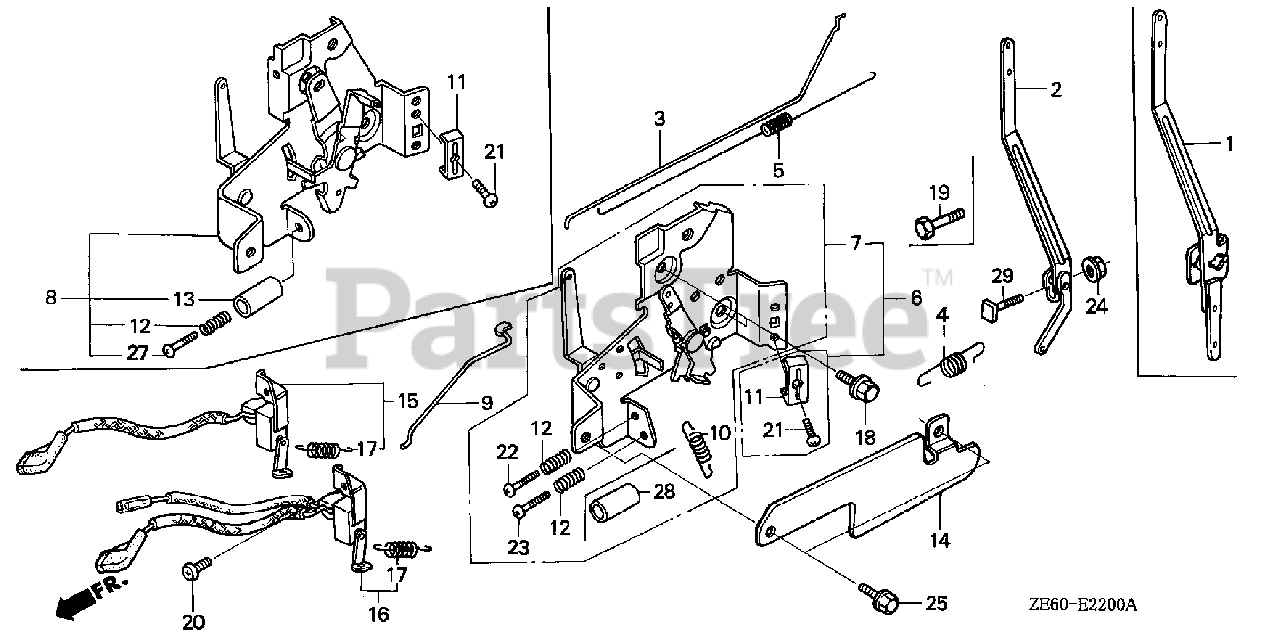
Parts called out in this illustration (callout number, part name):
2	ARM, GOVERNOR
3	ROD, GOVERNOR
4	SPRING, GOVERNOR
5	SPRING, THROTTLE RETURN
9	ROD, CHOKE
11	HOLDER, CABLE
12	SPRING, CONTROL ADJUSTING
14	PROTECTOR, CONTROL
16	SWITCH ASSY., ENGINE STOP
17	SPRING, SWITCH CONTROL
18	BOLT, FLANGE (6X14) (CT200)
20	SCREW, PAN (4X8)
21	SCREW, PAN (5X16)
24	NUT, FLANGE (6MM)
25	BOLT, FLANGE (6X10)
27	SCREW, PAN (5X20)
29	BOLT, GOVERNOR ARM
